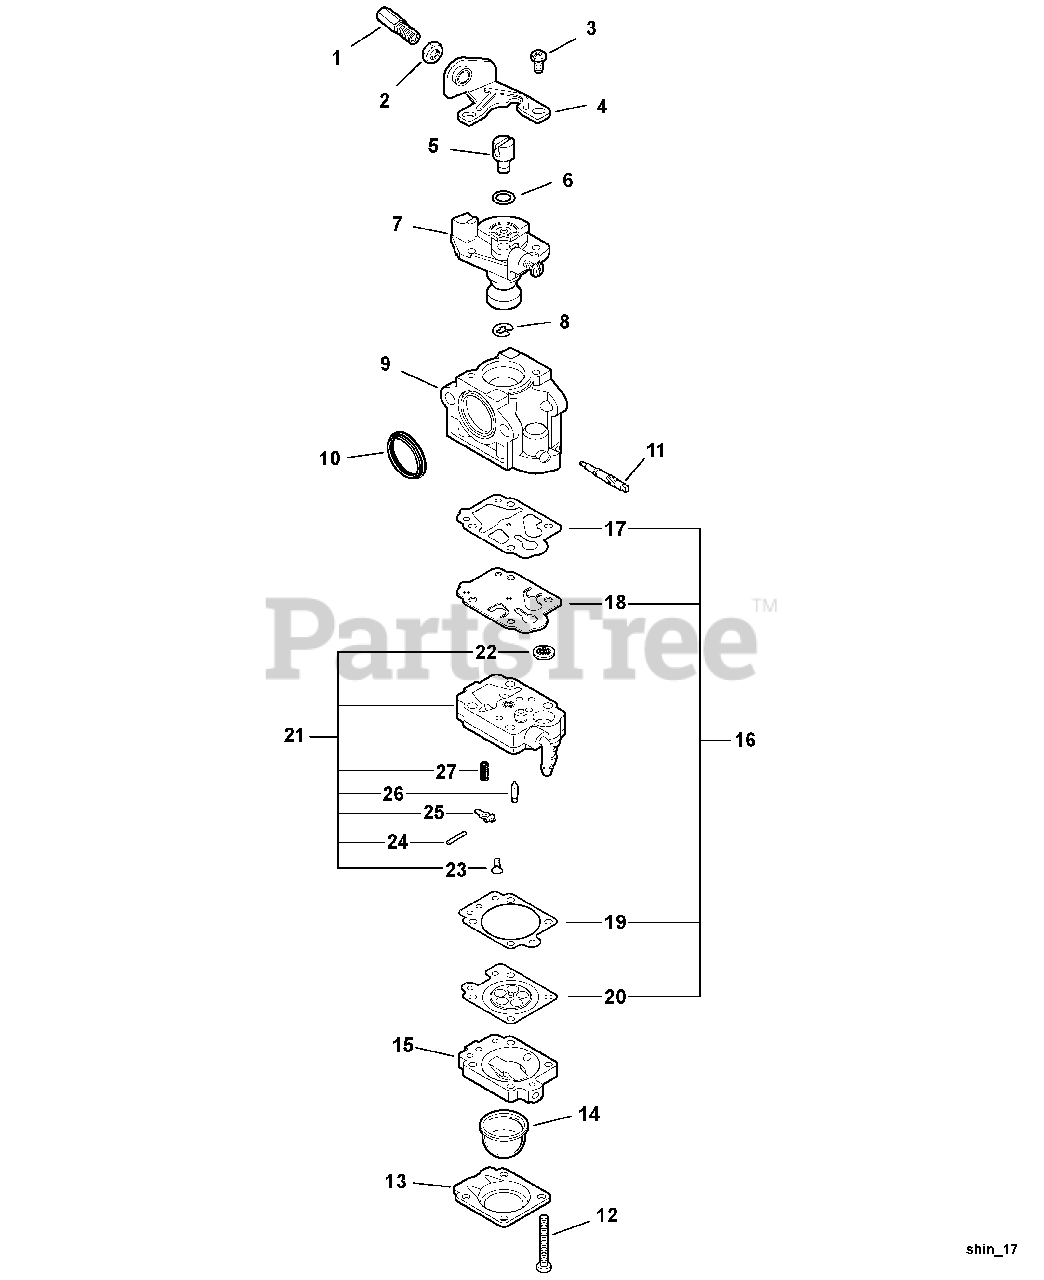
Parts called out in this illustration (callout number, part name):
1	NUT, CABLE ADJUST
2	NUT
3	SCREW
4	BRACKET, CABLE
5	SWIVEL
6	WASHER
7	THROTTLE VALVE ASSY
8	RING, RETAINING
9	BODY, CARBURETOR
10	SEAL
11	NEEDLE - HIGH SPEED
12	SCREW, PUMP COVER
13	RETAINER, PURGE BULB
14	BULB, PURGE
15	BASE, PURGE
16	DIAPHRAGM/GASKET KIT
17	GASKET, PUMP
18	DIAPHRAGM, PUMP
19	GASKET, METERING
20	DIAPHRAGM, METERING
21	PUMP BODY ASSY
22	STRAINER
23	SCREW, METERING LEVER PIN
24	PIN, METERING LEVER
25	LEVER, METERING
26	VALVE, INLET NEEDLE
27	SPRING, METERING LEVER
